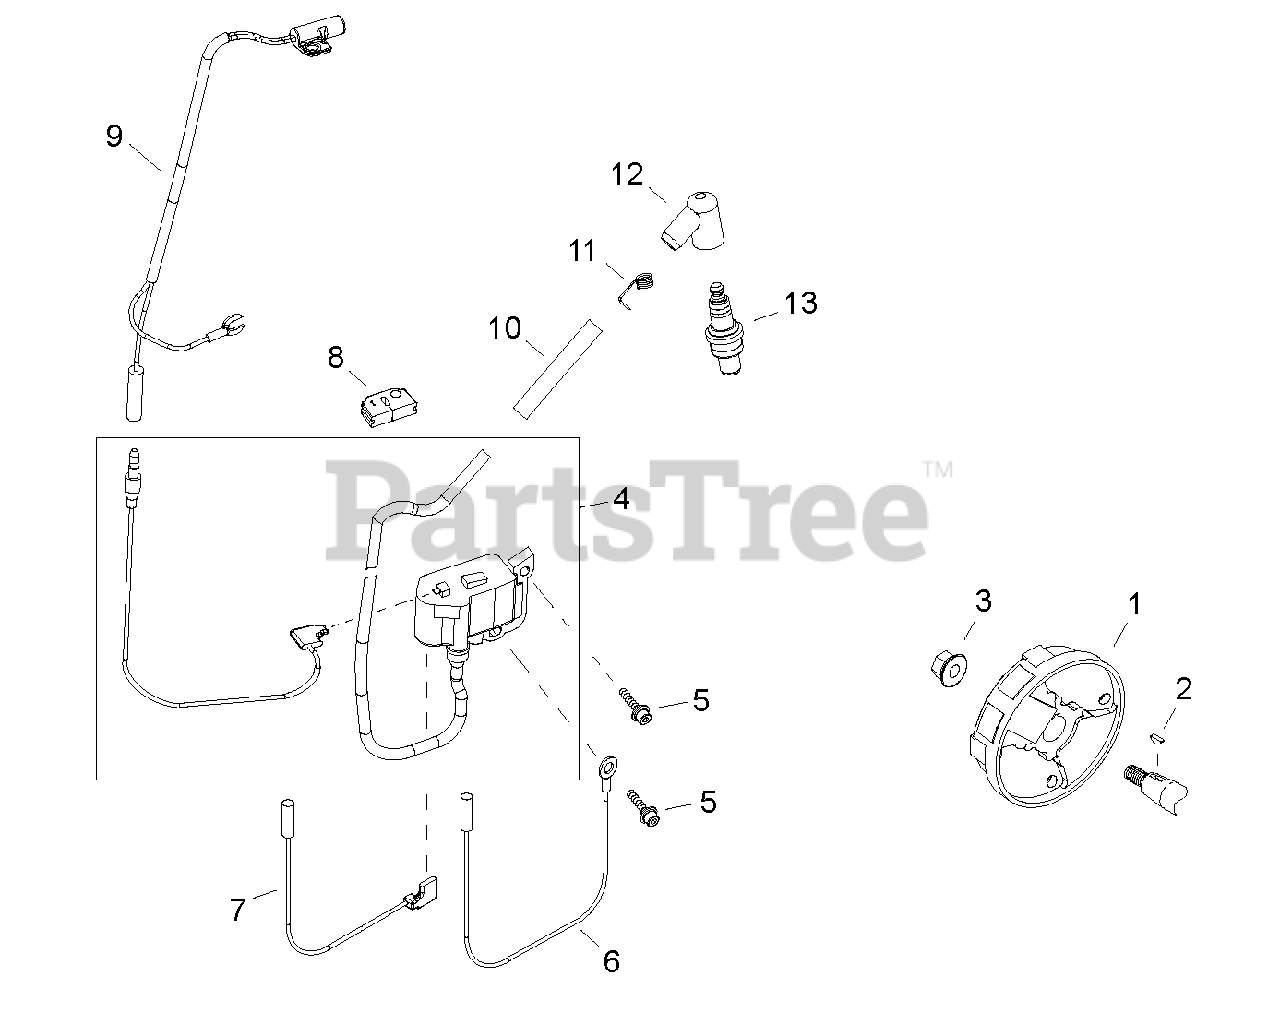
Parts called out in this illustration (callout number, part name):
1	FLYWHEEL
2	KEY, WOODRUFF 3×10
3	NUT M8
4	COIL ASSY, IGNITION
5	BOLT M4×20
6	LEAD - GROUND
7	LEAD 0.75 MM2 L= 175
8	GROMMET
9	SENSOR, THERMAL
10	TUBE, INSULATOR
11	TERMINAL, SPARK PLUG
12	CAP, SPARK PLUG
13	SPARK PLUG - CMR5H
